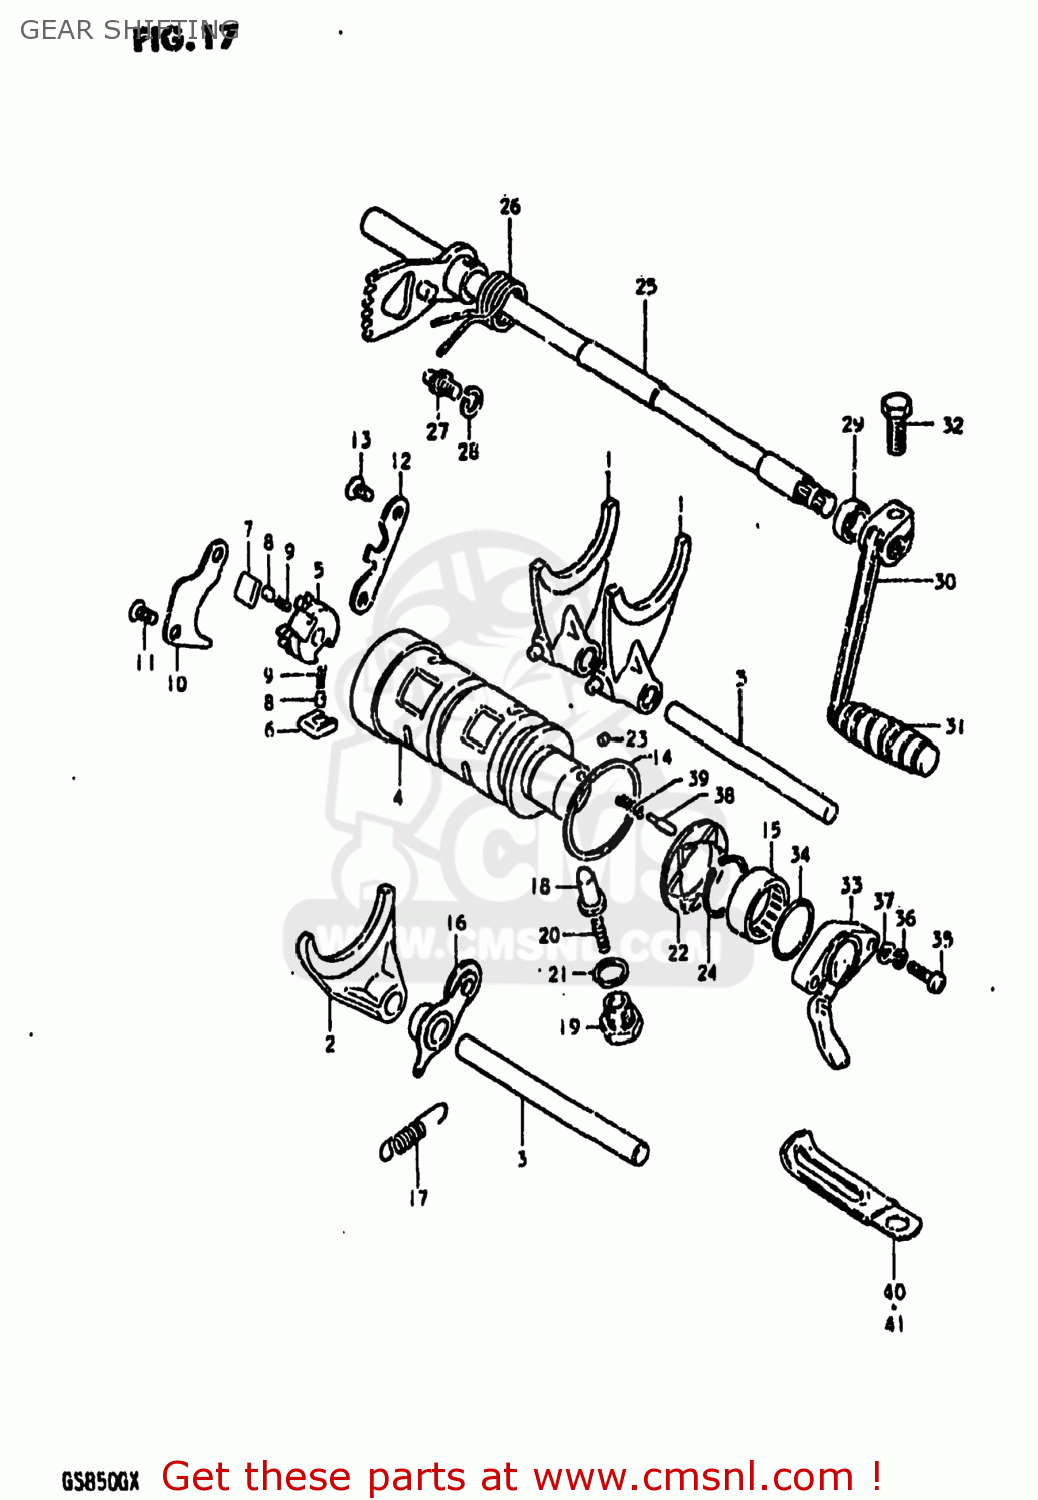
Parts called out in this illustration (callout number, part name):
1	FORK,GEAR SHIFT NO.1
2	FORK,GEAR SHIFT NO.3
3	SHAFT,GEAR SHIFT FORK
4	CAM,GEAR SHIFT
5	RETAINER,GEAR SHIFT CAM
6	PAWL,GEAR SHIFT NO.1
7	PAWL,GEAR SHIFT NO.2
8	PIN(5X8)
9	SPRING
10	LIFTER,GEAR SHIFT PAWL
11	SCREW
12	GUIDE,GEAR SHIFT CAM
13	SCREW
14	WASHER(40X45X1)
15	BEARING(25X32X12)
16	STOPPER,GEAR SHIFTING
17	SPRING
18	STOPPER,GEAR SHIFTING
19	HOLDER,GEAR SHIFT CAM STOP SPR
20	SPRING
21	GASKET(14X19.2X2) (NAS)
22	PLATE,GEAR SHIFT CAM STOPPER
23	PIN 4X6
24	CIRCLIP
25	SHAFT,GEAR SHIFT
26	SPRING
27	STOPPER,GEAR SHIFT CAM
28	WASHER
29	OIL SEAL
30	LEVER ASSEMBLY,GEAR SHIFTING
31	RUBBER,GEAR SHIFT PEDAL
32	BOLT
33	TERMINAL BASE ASSY,GEAR SHIFT
34	O-RING (D:2.4 ID:26.2)
35	SCREW
36	LOCK WASHER
37	WASHER
38	PIN(5X15.5)
39	SPRING
40	CLAMP
41	CLAMP
